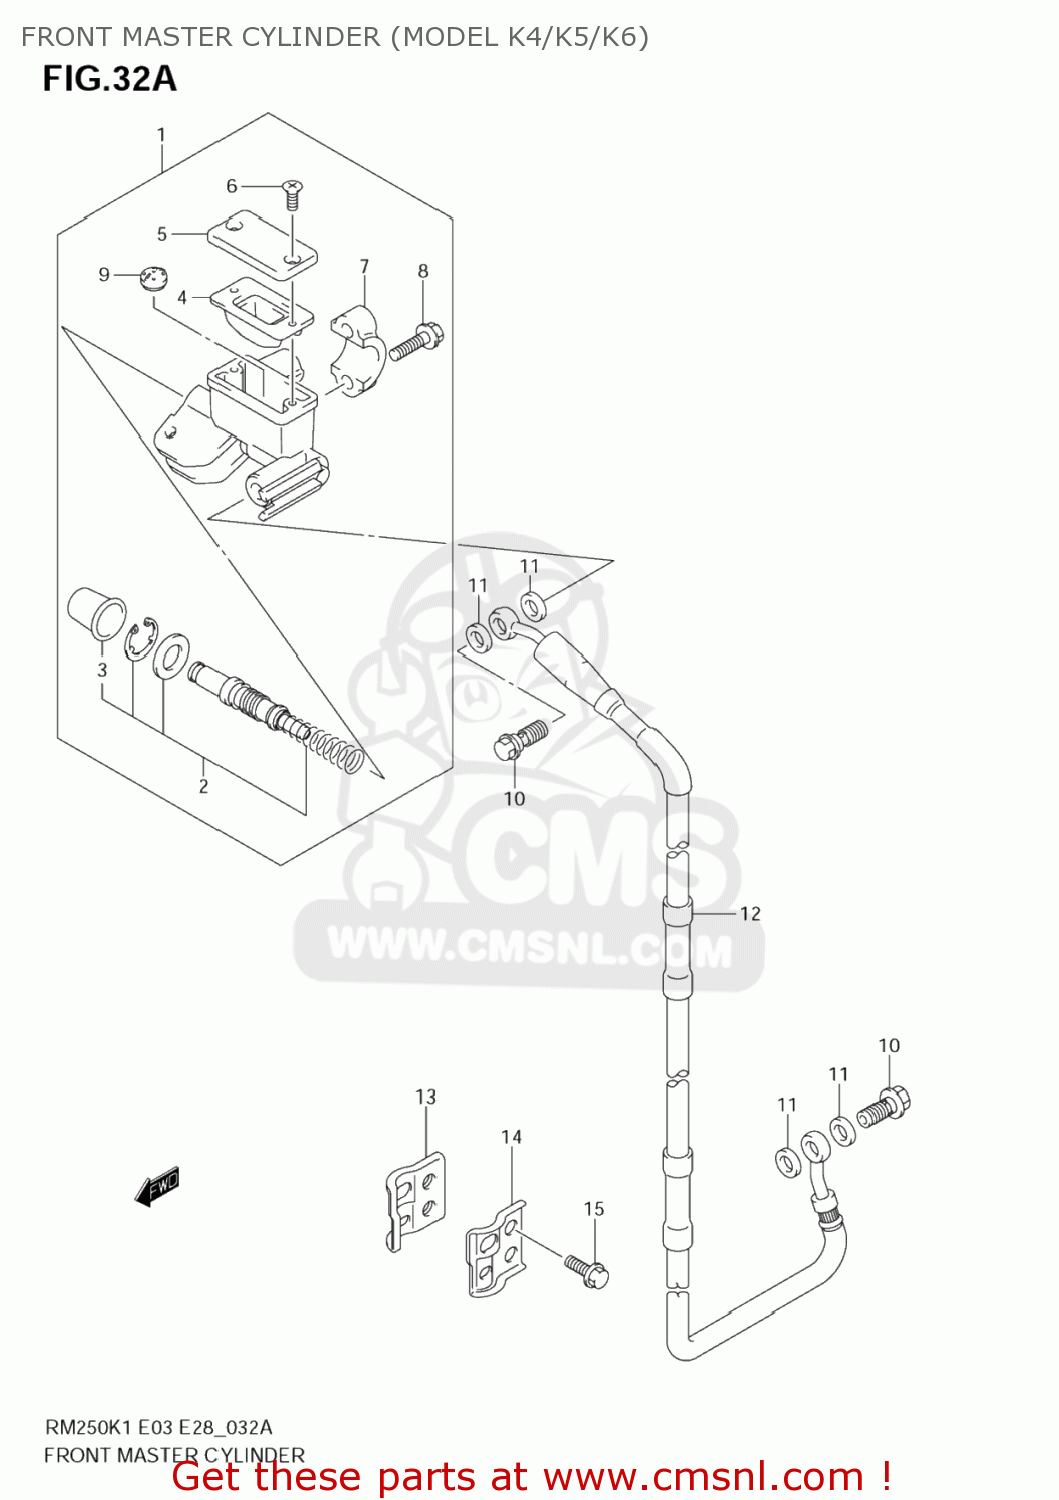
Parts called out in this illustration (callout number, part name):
1	CYLINDER ASSY,FR MASTER
2	PISTON & CUP SET
3	BOOT
4	DIAPHRAGM
5	CAP
6	SCREW
7	HOLDER
8	BOLT
9	SEPARATOR
10	BOLT UNION
11	WASHER(10X15X1.5)
12	HOSE,FRONT BRA
13	CLAMP,FR BRAKE HOSE INNER
14	CLAMP,FR BRAKE HOSE OUTER
15	BOLT(6X16)
